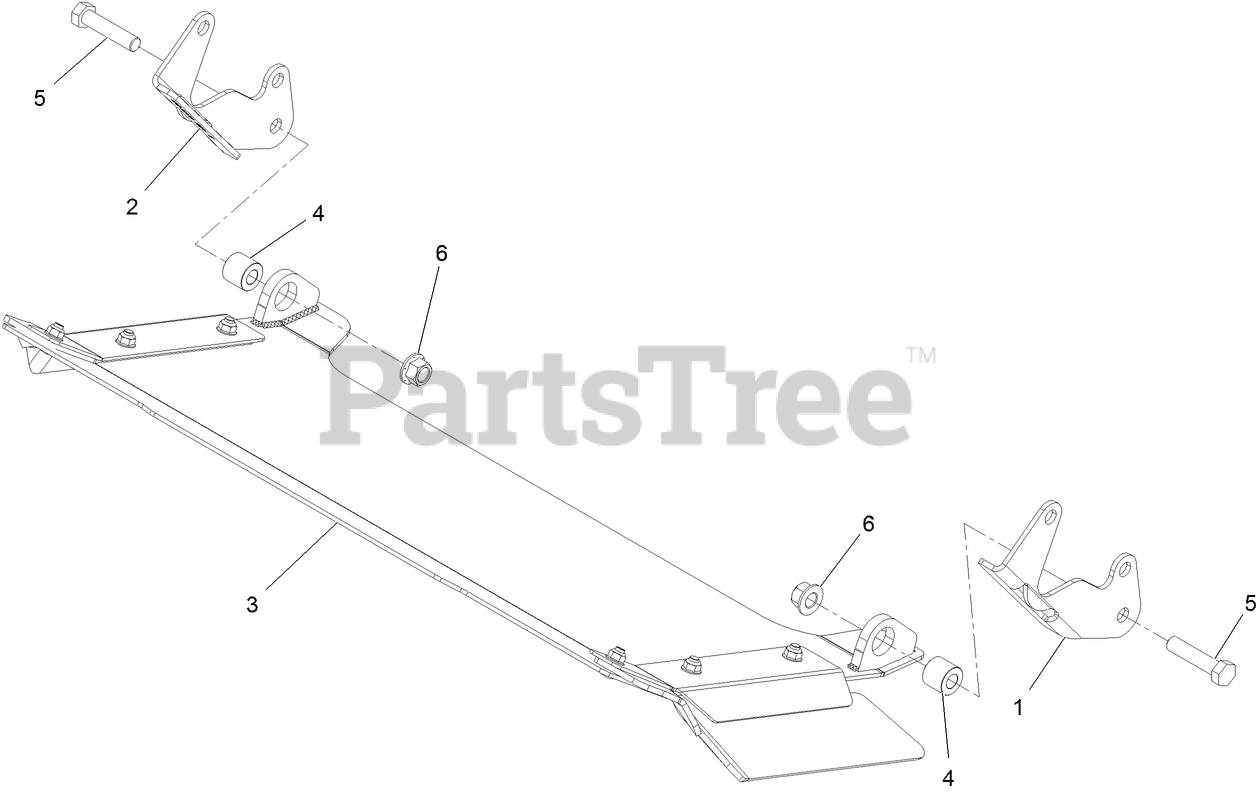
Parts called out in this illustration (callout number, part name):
1	BRACKET-DISCHARGE MOUNT,
2	BRACKET-DISCHARGE MOUNT,
3	DISCHARGE TUNNEL ASM
4	BUSHING-SLEEVE
5	SCREW-HH
6	Nut-Lock 1/2-13
